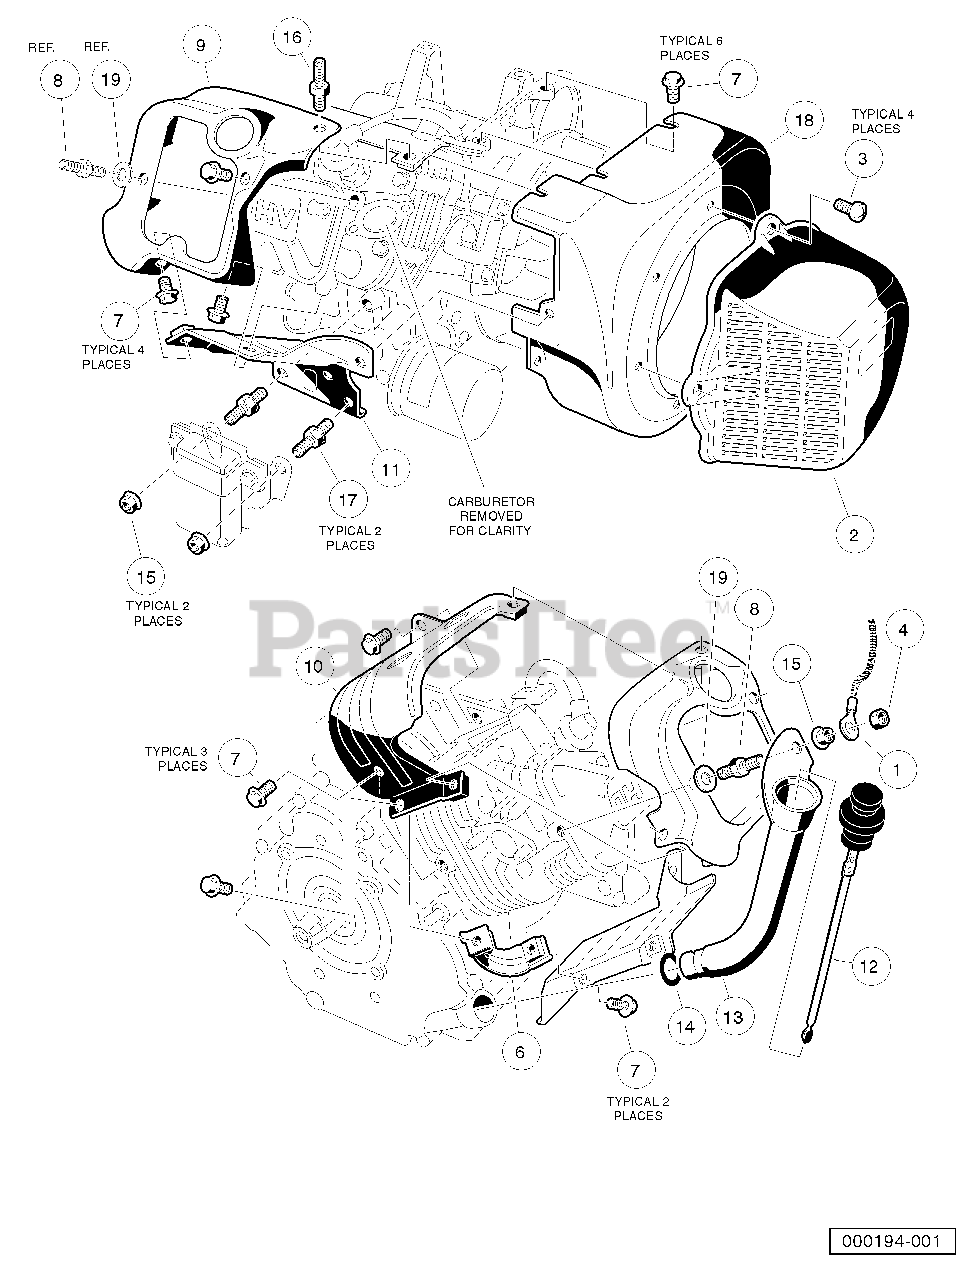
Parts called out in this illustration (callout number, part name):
1	Wire Assembly, #10, Uninsulated
2	Shroud, Fan
3	Screw, M6-1.00 X 10mm Pan Hd
4	Locknut, M6-1.00 Nylon Insert
5	Engine, FE290
7	Bolt, Flange Head, M6 x 1 x 12 mm
8	Bolt, Two-Ended
9	Shroud, Engine, FE290D
10	Shroud, Engine, FE290D
11	Shroud, Engine, FE290D
13	Tube, Oil Filler, FE290D
16	Screw, M6-1.00 Stud
17	Stud, M6-1.00, Two-Ended
18	Housing, FE290 Fan
19	Washer, 6 mm Flat
